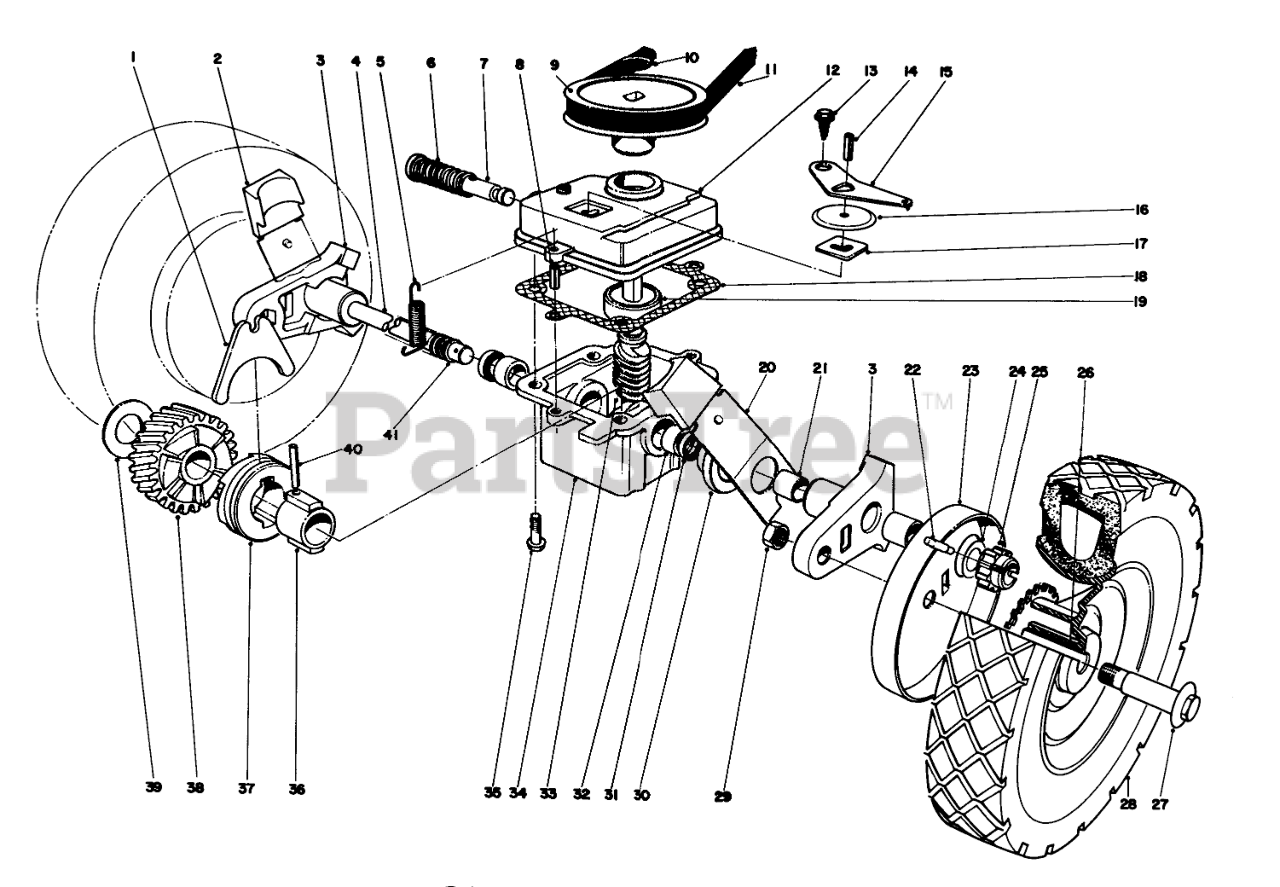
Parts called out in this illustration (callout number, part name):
1	SHIFTER FORK
2	Knob
3	PIVOT ARM ASM
4	Drive Shaft
5	TENSION SPRING
6	SPRING
7	Shift Rod
8	3/16 X 1/2 ROLL PIN
9	PULLEY
10	PUSH-ON 93-3236
11	V BELT
12	GEAR CASE COVER
13	Screw
14	PIN-ROLL
15	SHIFTER ARM
16	TRANS DUST COVER
17	LATCH PLATE
18	GASKET
19	Bearing
20	Spring Arm
21	BUSHING
22	PIN-GROOVED
23	WHEEL COVER
24	WASHER-THRUST
25	Pinion
26	WHEEL BUSHING
28	Wheel & Tire
29	Nut
30	End Cap
31	Seal
32	Bushing
33	WORM SHAFT
34	Gear Case
35	Screw
36	SLEEVE
37	CLUTCH JAW
39	THRUST WASHER
40	COIL PIN
41	COVER-SHAFT, DRIVE
